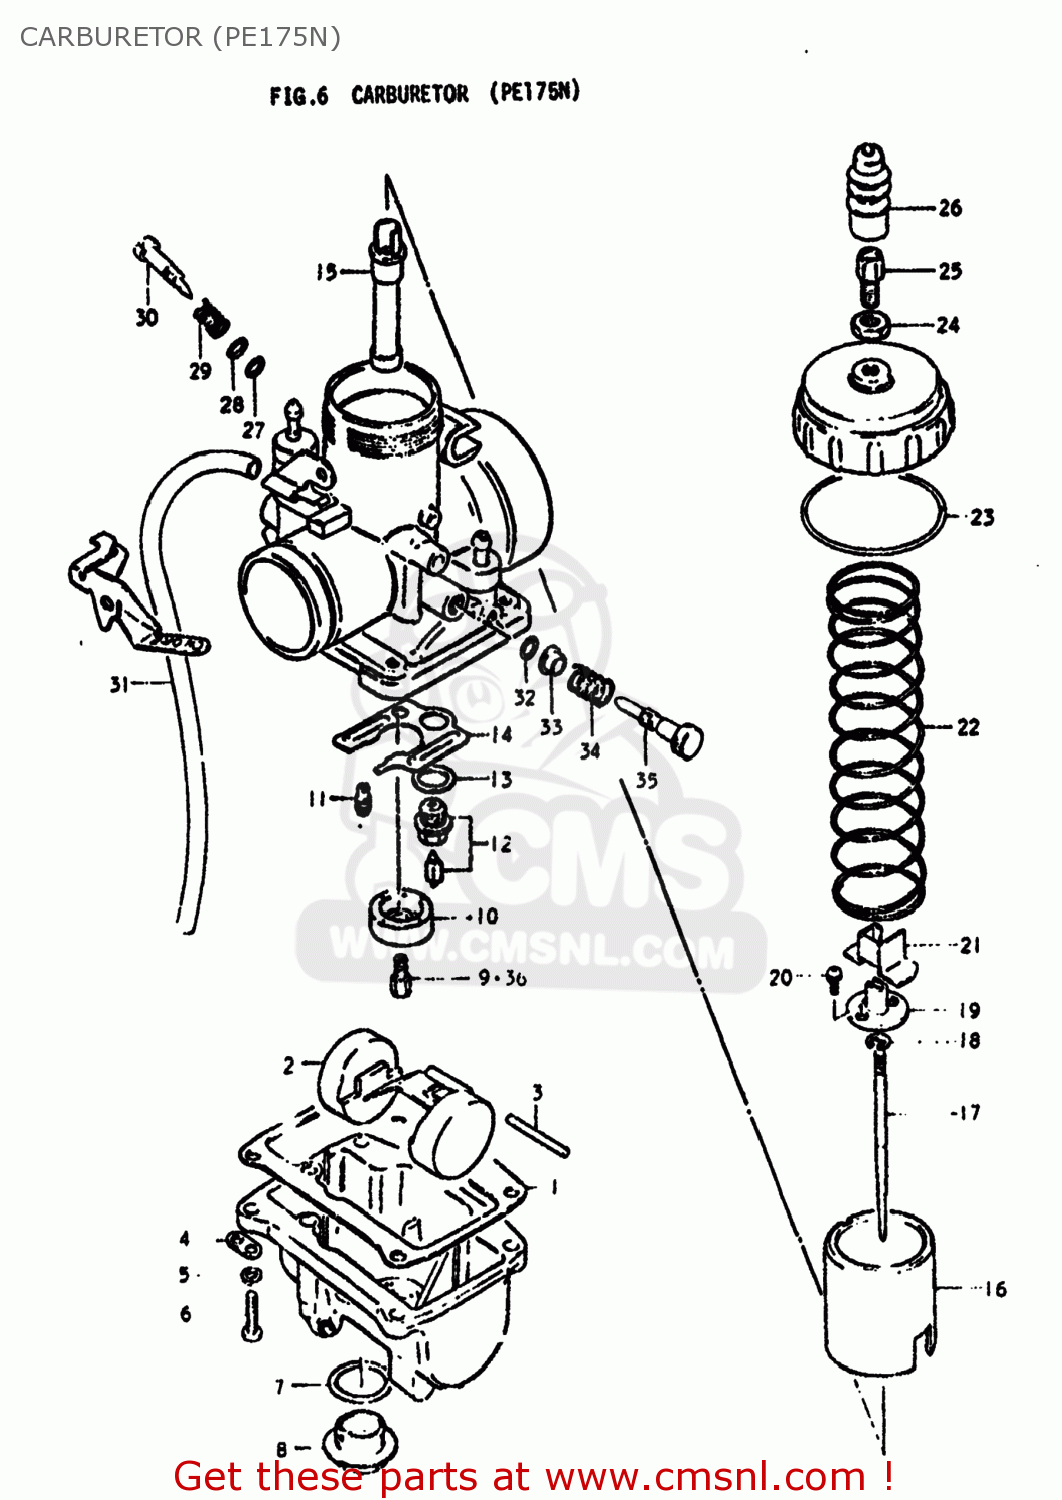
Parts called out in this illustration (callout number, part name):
1	GASKET,FLOAT CAHMBER (NAS)
2	FLOAT
3	PIN,FLOAT
4	PLATE
5	LOCK WASHER
6	SCREW
7	O RING,DRAIN PLUG
8	SCREW,GUIDE
9	JET,MAIN (220)
10	RING
11	JET
12	VALVE ASSEMBLY,NEEDLE
13	GASKET,MAIN JET HOLDER (NAS)
14	PLATE
15	JET,NEEDLE
16	VALVE,THROTTLE
17	NEEDLE,JET
18	CLIP
19	CONNECTOR
20	SCREW
21	COVER,HOLDER
22	SPRING,THROTTLE VALVE RETURN
23	O-RING,MIXING CHAMBER
24	NUT
25	ADJUSTER,CABLE
26	CAP,CABLE ADJUSTER
27	O RING
28	WASHER,PILOT AIR SCREW
29	SPRING
30	SCREW,PILOT AIR
31	HOSE
32	O-RING
33	COVER
34	SPRING,THROTTLE STOP
35	SCREW,THROTTLE STOP
36	JET
